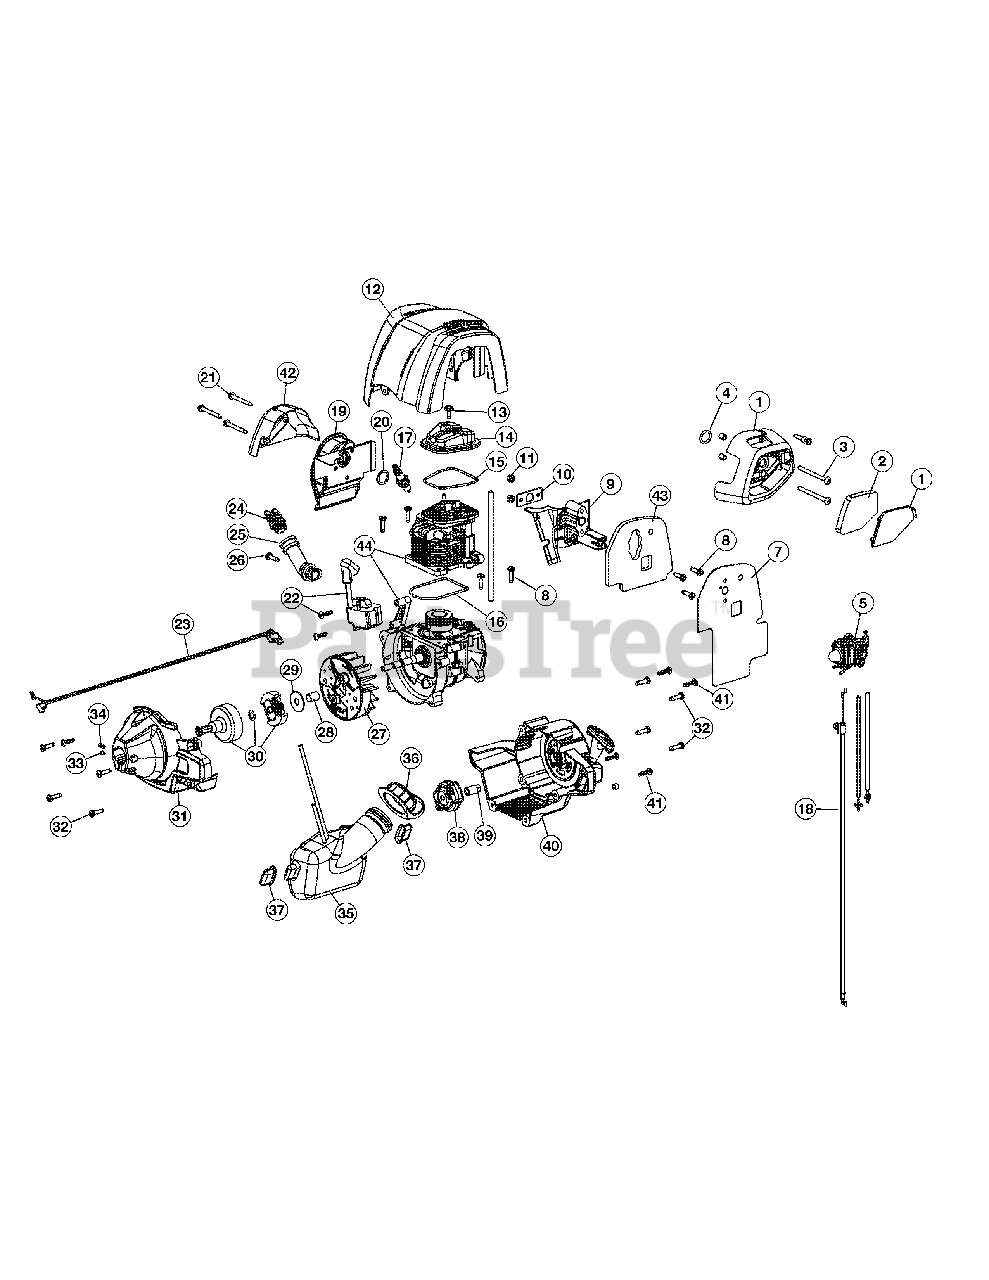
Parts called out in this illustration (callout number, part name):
1	Air cleaner Assembly (Incl. Ref No. 2 & 3)
2	Air Filter
4	Carburetor O-Ring
5	Carburetor Assembly
7	Carburetor Baffle
8	Screw
10	Insulator Gasket
12	Engine Cover
14	Valve Cover
15	Valve O-Ring
16	Cylinder O-Ring
17	Spark Plug
18	Throttle Cable
19	Muffler Assembly
20	Muffler Gasket
21	Muffler Bolt
22	Module Assembly
23	Lead Wires
24	Oil Plug Assembly
25	Oil Fill Tube Assembly (Incl. Ref No. 25)
29	Clutch Washer
30	Clutch Assembly
31	Clutch Cover Assembly
33	Anti-rotation Screw
34	Clamp Screw & Nut
35	Fuel Tank (Incl. Ref No. 35)
37	Fuel Tank Pad
38	Pawl Assembly
39	Electric Start Adapter
40	Starter Cover Assembly
42	Muffler Shield
43	Carburetor Heat Shield
44	Short Block Assembly
